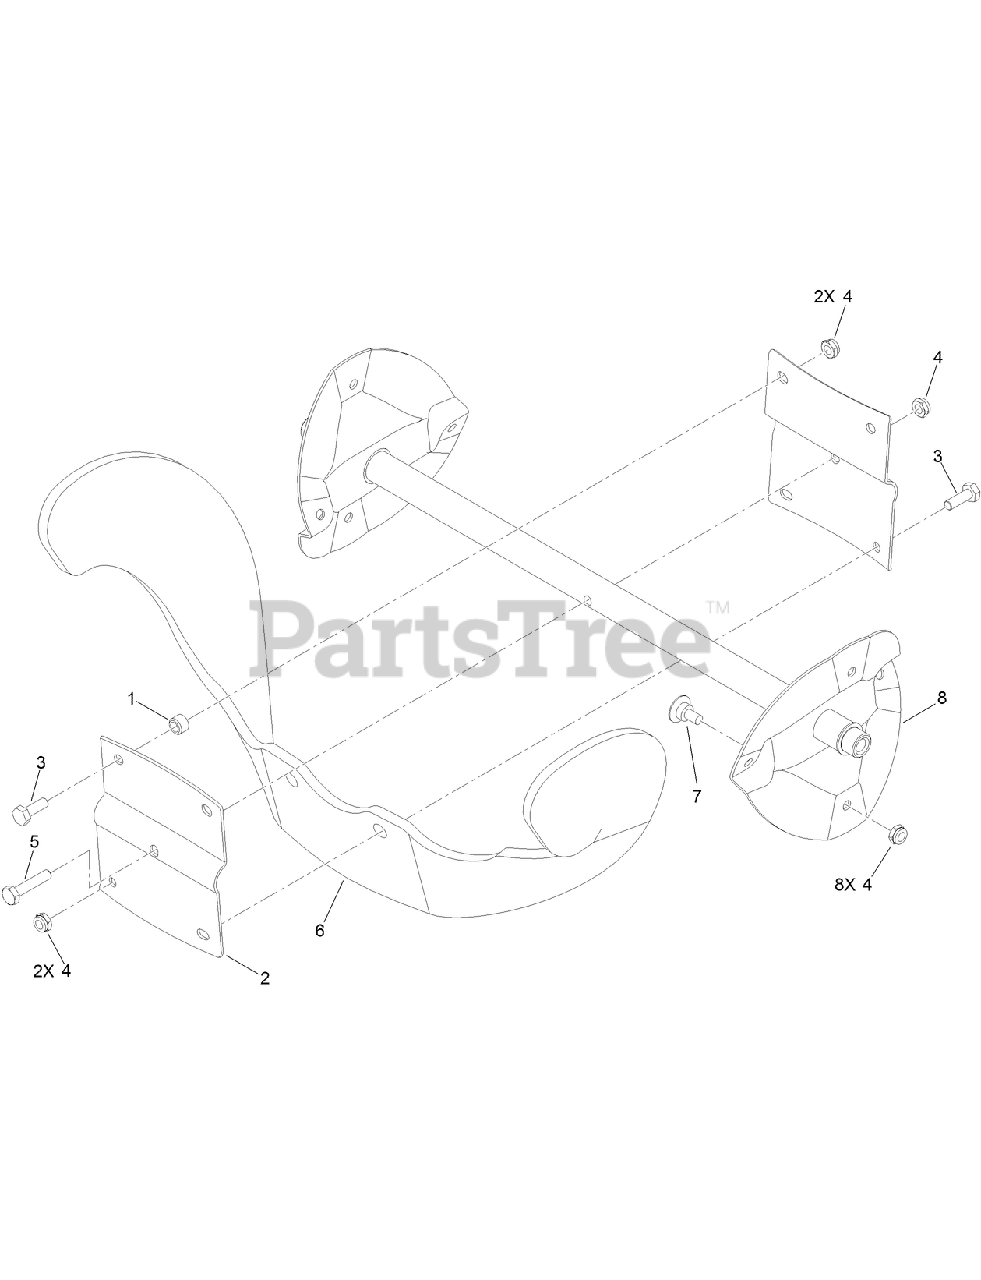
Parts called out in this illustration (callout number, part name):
1	SPACER-BLADE, ROTOR
2	HALF-ROTOR
3	SCREW-HH
4	NUT-LOCK, NI
5	SCREW-HH
6	BLADE-ROTOR
7	SCREW
8	ROTOR KIT
